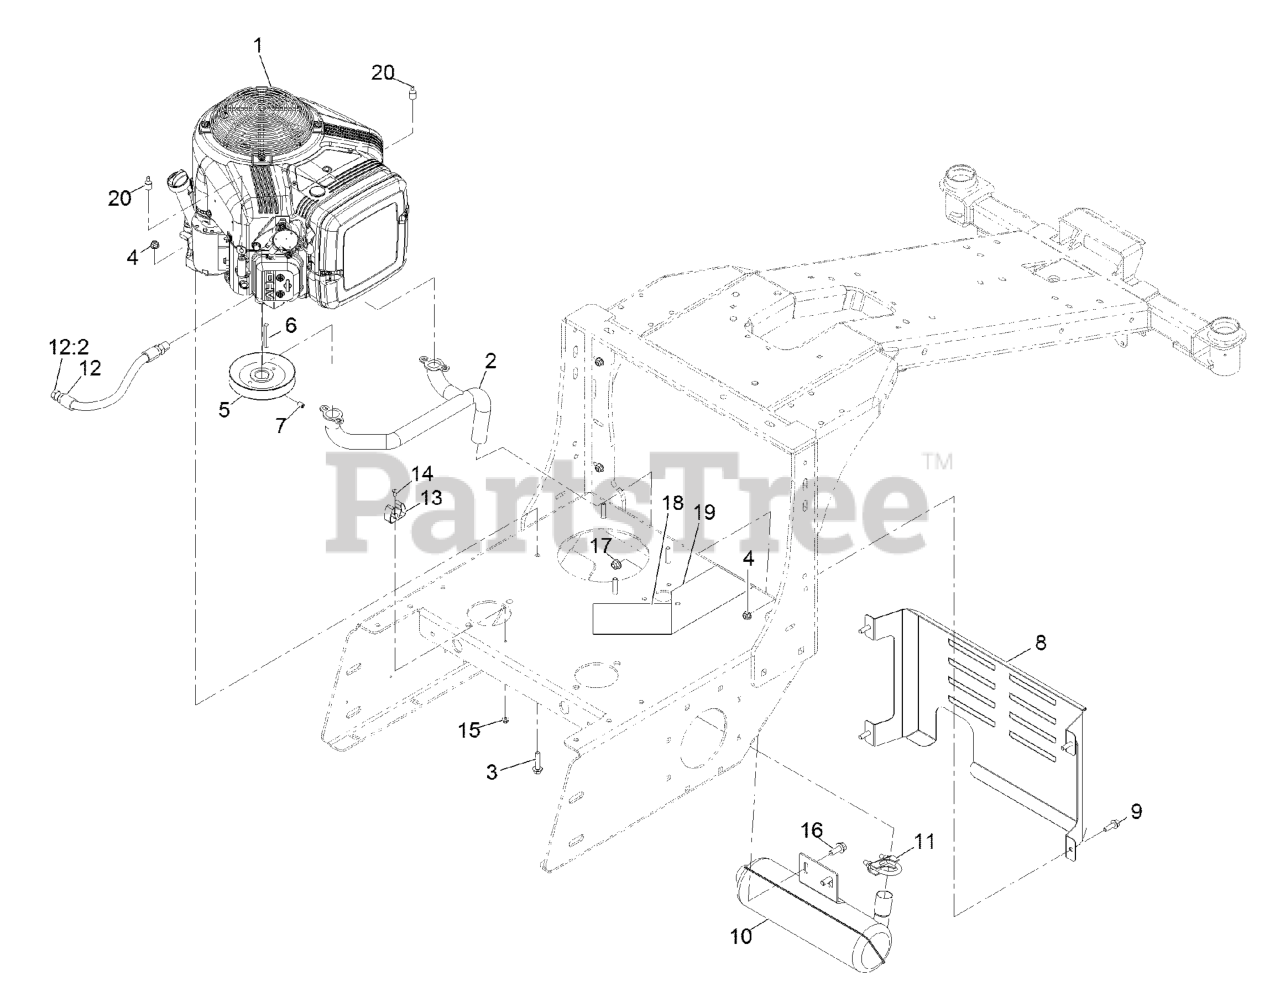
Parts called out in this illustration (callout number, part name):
1	Engine - Vanguard
2	18 HP EXHAUST MANIFOLD 4
3	SCREW-HHF
4	NUT-HF, NI
5	PULLEY-DRIVE
7	Setscrew-HSH
8	GUARD-ENGINE, AE
9	SCREW-HH
10	23HP BRIGGS MUFFLER(18HP
11	Clamp-Muffler
12	HOSE-DRAIN,3/8X15.75W/JIC
13	Holder-Tool, Clip
14	Screw-HSBH
15	Nut-Hex Flange
16	SCREW-HHF 3/8-16 X 1
17	NUT-HF, NI
18	ADHESIVE BACK, HEAT BARRI
19	TAPE-HEAT
20	Tube-Heat Shrink, 1/2
